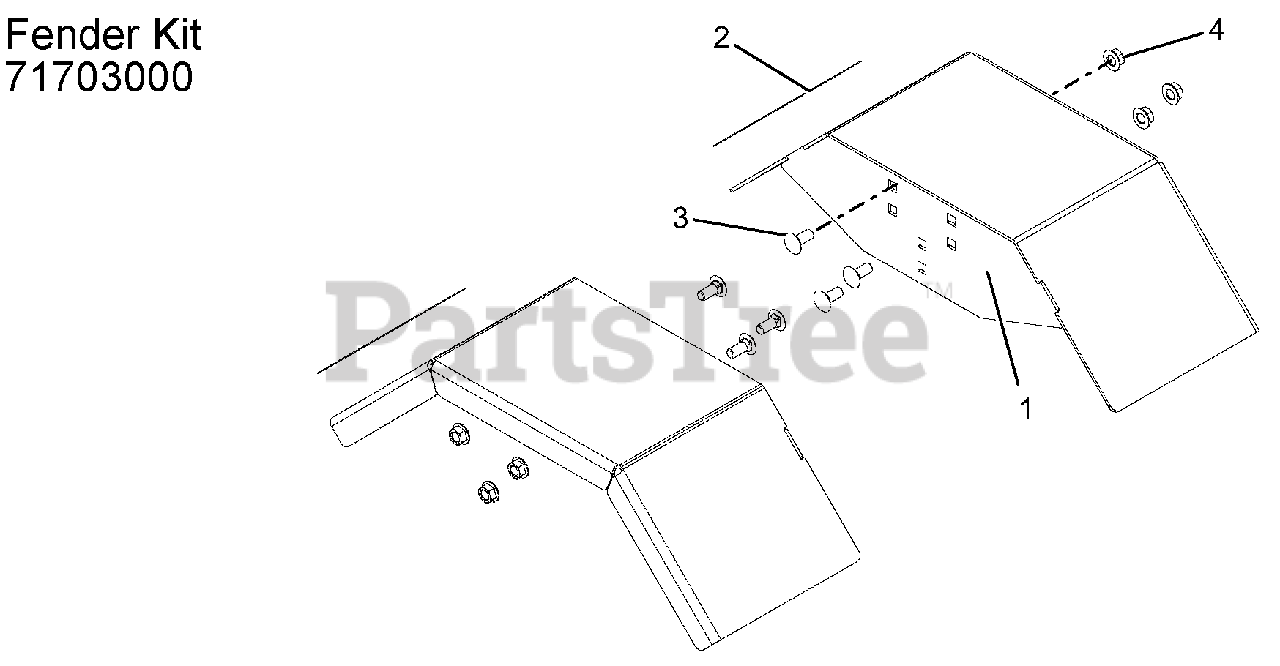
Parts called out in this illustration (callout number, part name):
1	WLDMT, FENDER
2	DECAL, ARIENS JEWEL (LARGE)
3	@BLT-RDHDSQNK .31-18X.75 G5YZ
4	@NUT-LK-TOP-FLG .31-18 YWZC
